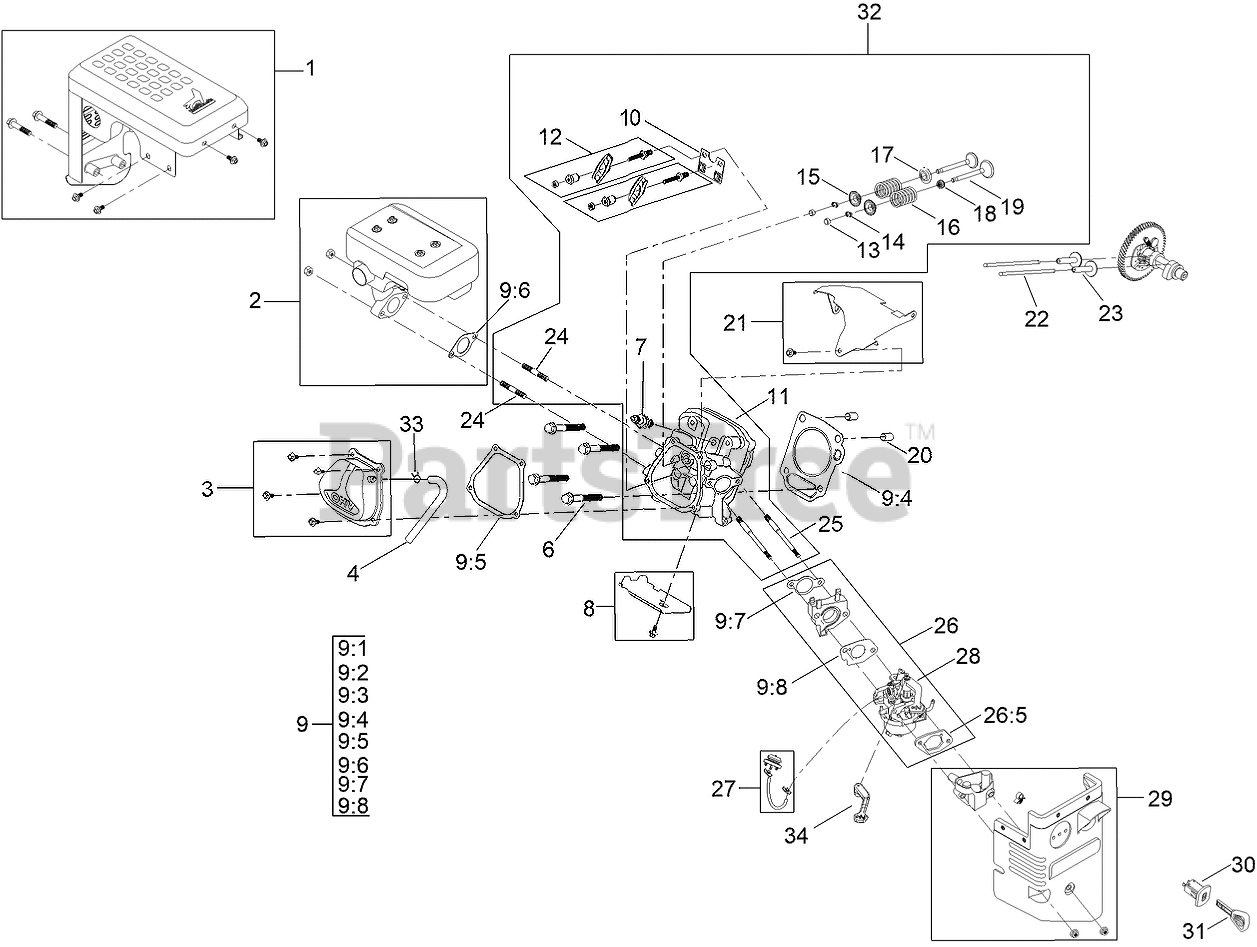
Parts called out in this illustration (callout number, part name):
1	MUFFLER SHIELD KIT
2	MUFFLER KIT
3	VALVE COVER KIT
4	TUBE-BREATHER
6	SCREW-HHF
8	LOWER HEAT SHROUD KIT
9	SEAL AND GASKET KIT
9:1	SEAL-OIL
9:2	SEAL-OIL
9:3	GASKET-COVER, CRANKCASE
9:4	GASKET-HEAD, CYLINDER
9:5	GASKET-COVER, VALVE
9:6	GASKET-EXHAUST
9:7	GASKET-CARBURETOR
9:8	GASKET-CARBURETOR
10	PLATE-GUIDE, PUSH ROD
11	HEAD-CYLINDER
12	ROCKER ARM ASM
13	ROTATOR-VALVE
14	KEEPER-VALVE
15	RETAINER-SPRING, VALVE
16	SPRING-VALVE
17	SEAT-SPRING, VALVE
18	SEAL-STEM, VALVE
19	VALVE KIT
20	PIN-DOWEL
21	UPPER HEAT SHROUD KIT
22	ROD-PUSH
23	LIFTER-VALVE
24	STUD-MOUNT, MUFFLER
25	STUD-MOUNT, CARBURETOR
26	COMPLETE CARB SERVICE KIT
26:5	GASKET-COATED, RUBBER
27	PRIMER KIT
28	CARB REPAIR KIT WITH GASKETS
29	HEATER BOX KIT
30	SWITCH-KEY
32	COMPLETE HEAD ASM
33	CLAMP-HOSE
34	LEVER-CHOKE
